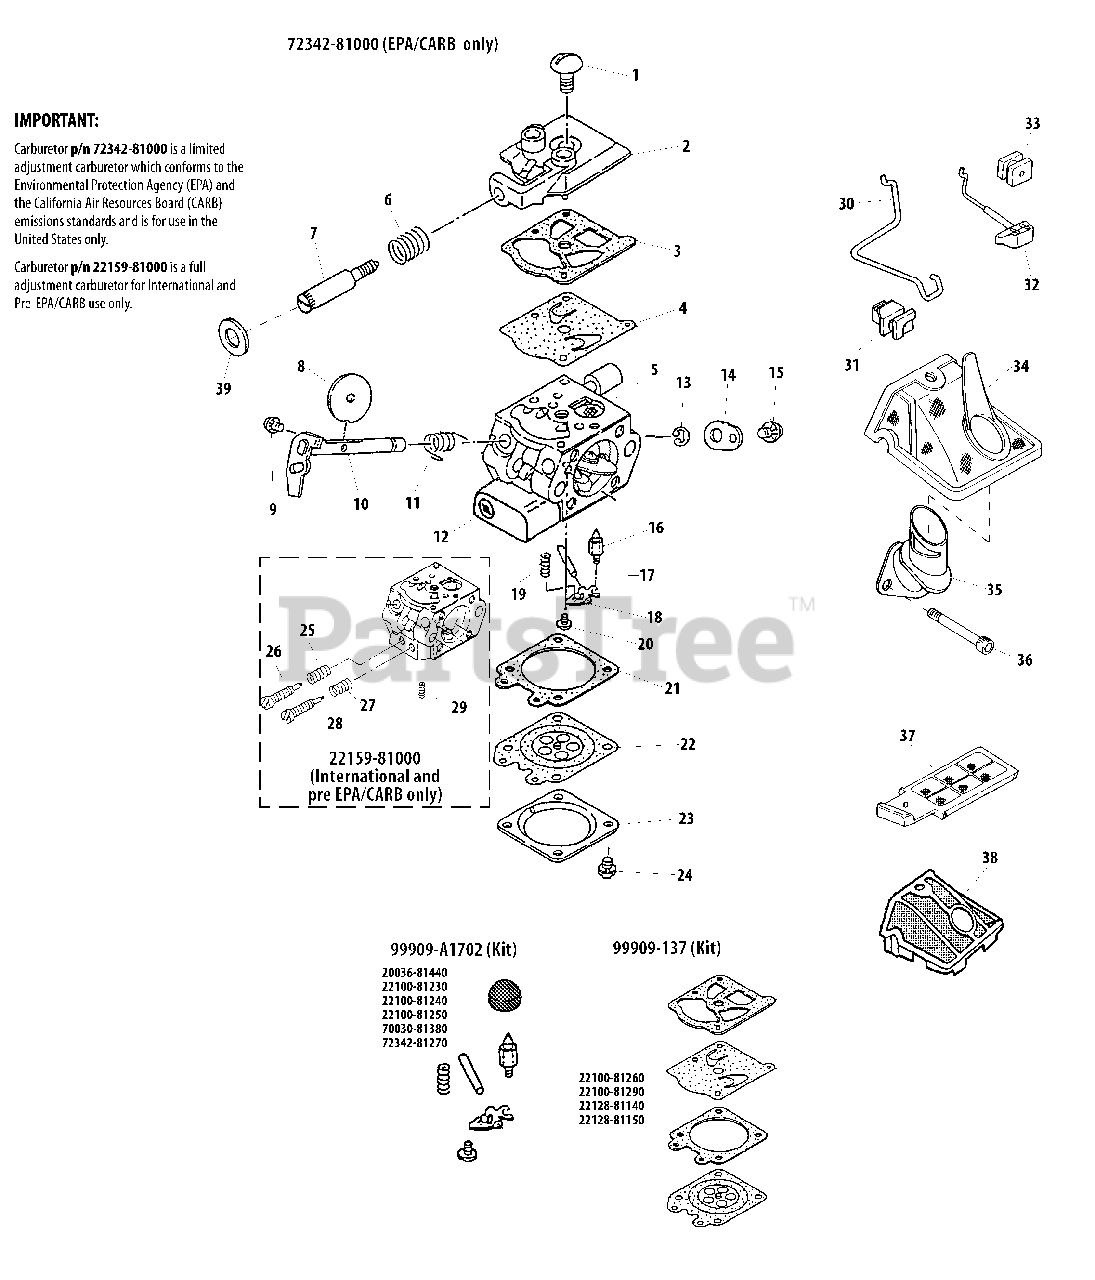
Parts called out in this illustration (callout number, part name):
1	SCREW, PUMP COVER
2	COVER, PUMP
3	GASKET, PUMP
4	DIAPHRAGM, PUMP
5	STRAINER
6	SPRING
7	SCREW, IDLE ADJUST
8	VALVE, THROTTLE
9	SCREW
10	SHAFT, THROTTLE
11	SPRING, RETURN
12	CAP, LIMITER
13	RING, RETAINING
14	TRIGGER, THROTTLE
15	SCREW
16	VALVE, INLET NEEDLE
17	PIN, METERING LEVER
18	LEVER, METERING
19	SPRING, METERING LEVER
20	SCREW, METERING LEVER PIN
21	GASKET, METERING
22	DIAPHRAGM, METERING
23	COVER, DIAPHRAGM
24	SCREW
25	SPRING
26	NEEDLE - LOW SPEED
27	SPRING
28	NEEDLE - HIGH SPEED
29	SPRING, METERING LEVER
30	ROD, THROTTLE
31	GROMMET
32	ROD, CHOKE
33	GROMMET
34	FILTER, AIR
35	ELBOW
36	SCREW - 5X40
37	PRE-FILTER
38	FILTER, AIR - FLOCKED
39	SEAL
22159-81000	CARBURETOR
72342-81000	CARBURETOR
99909-137	DIAPHRAGM/GASKET KIT
99909-A1702	REPAIR KIT
